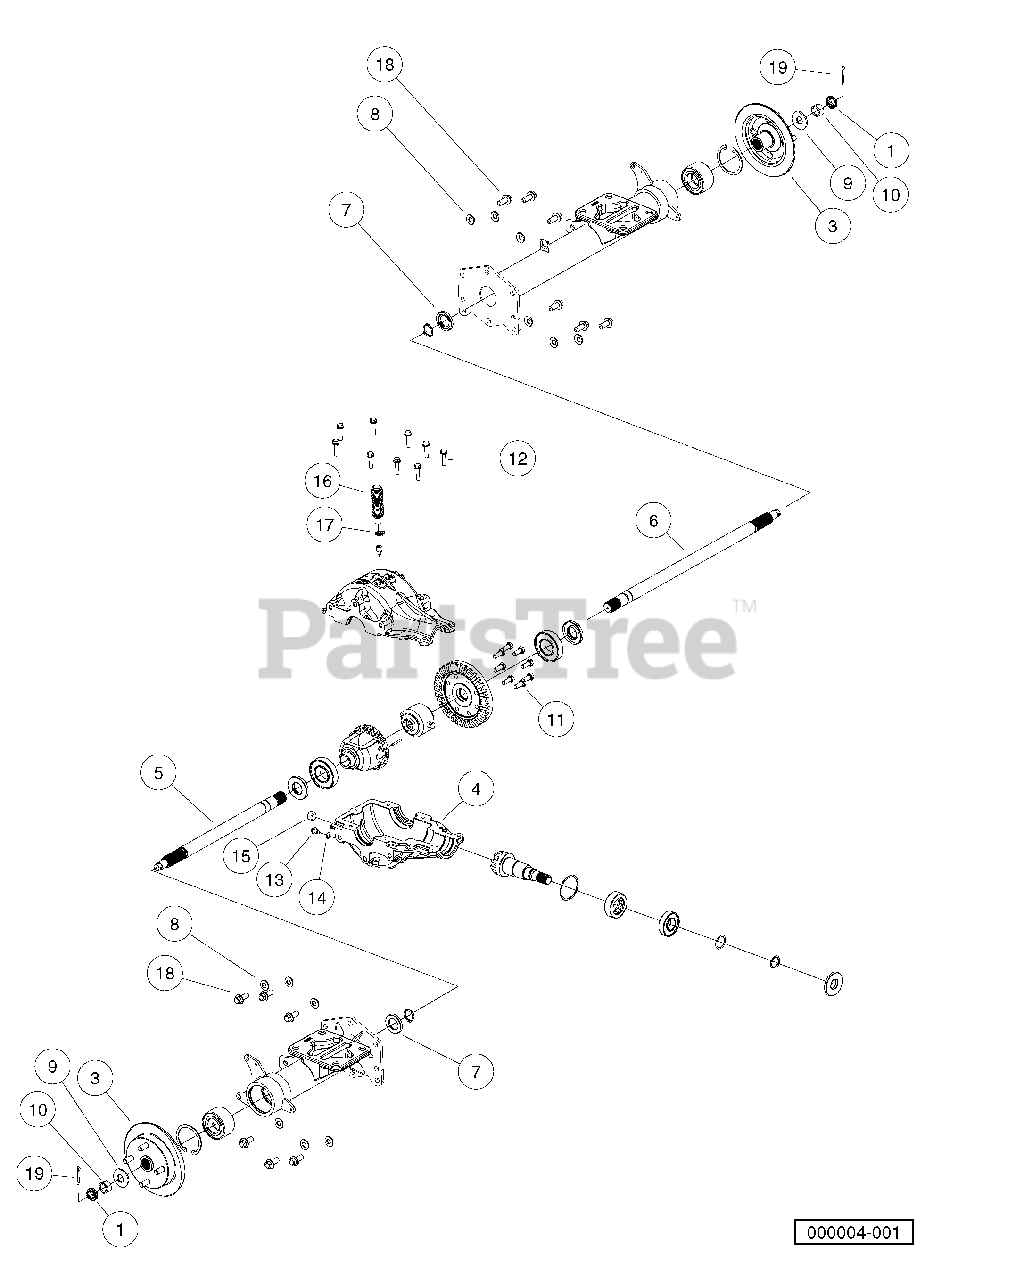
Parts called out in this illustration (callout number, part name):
1	Axle, Rear, Guard Mounts
2	Locking Cap, Nut
3	Assy, Rotor, Brake, Rear
4	Gearcase, Lower, Machined
5	Axle, Right-hand
6	Axle, Left-Hand
7	Washer,counterbored 51 X 30
8	Washer, Bellevle, 1.063 X .043
9	Washer, Belleville, 49 X 4
10	Nut, Hex, M20 X 1.5 , Modified
11	Screw, M10 X 25
12	Screw,hex Flange, M8 X 35
13	Plug,3/8-16, Hex Flange
14	Washer, .625 X .382 X .60
15	Plug, Square Skt, 1/12-14, Ptf
16	Bellows, Vent, Upper Housing
17	Clamp, Hose, Dw-9.5
18	Screw, Hex Fl, M12 X 1.75 X 30
19	Pin, Cotter, 5/32 X 1.25
